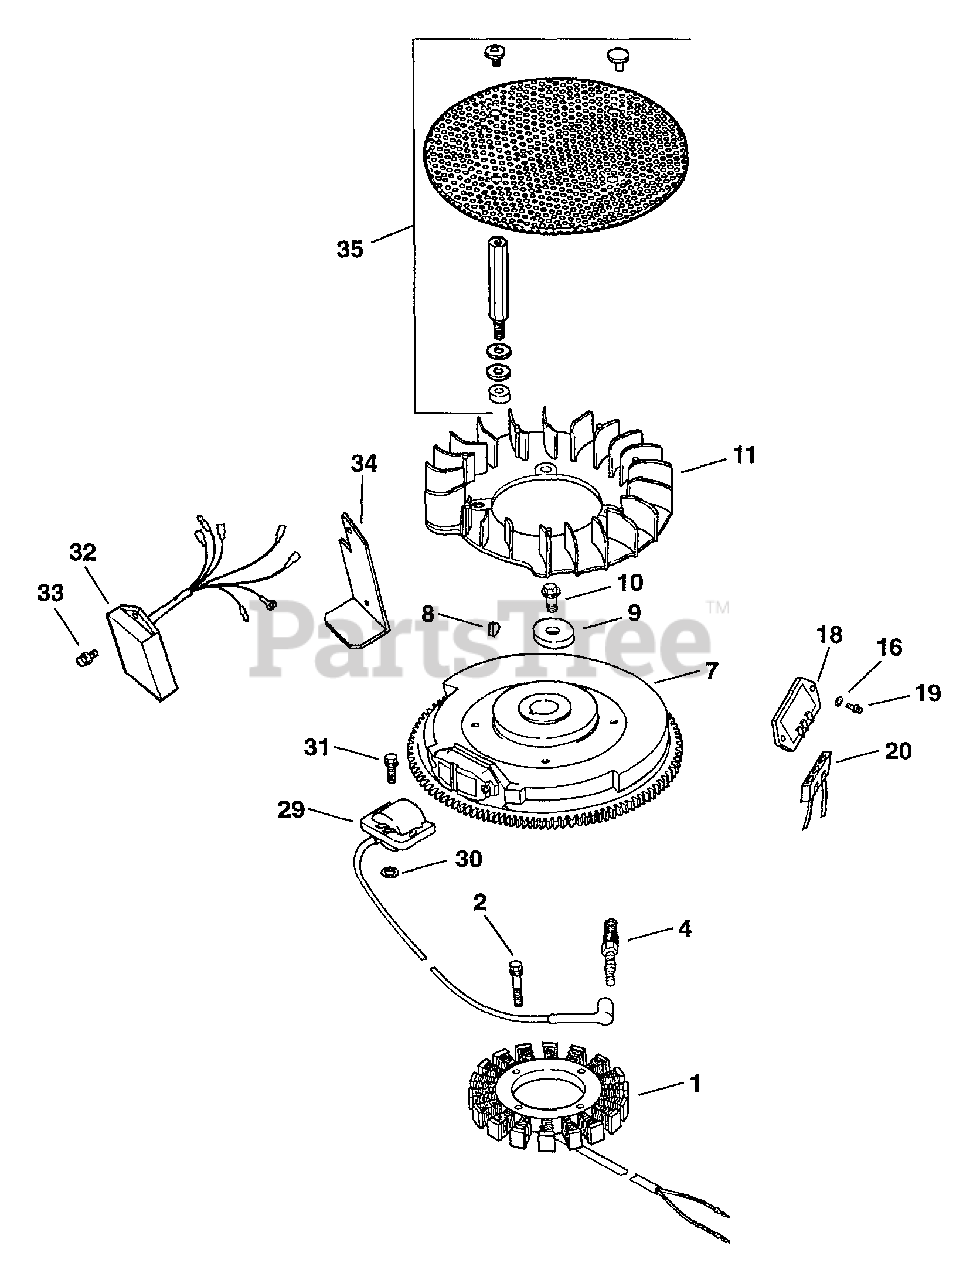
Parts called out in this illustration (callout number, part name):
1	KIT - USE 54 755 09
2	SCREW - USE M-548025
4	PLUG, SPARK (STD)
7	FLYWHEEL, PAINTED-USE 24 025 55-S
8	KEY, 3/16" X 5/8"
9	WASHER, FLAT 13/32"
10	SCREW, FLG M10X1.5X45 - (#25086361S)
11	FAN (KM)-USE 24 157 15-S
16	WASHER, FLAT 3/16"
19	SCREW, PHL HD #11-16X7/8"
20	CONNECTOR, BODY (KM)-USE 25 155 41-S
35	Screen, metal chopper grass
2417612-S	HARNESS, WIRING
2451804	LEAD - USE 25 518 34
